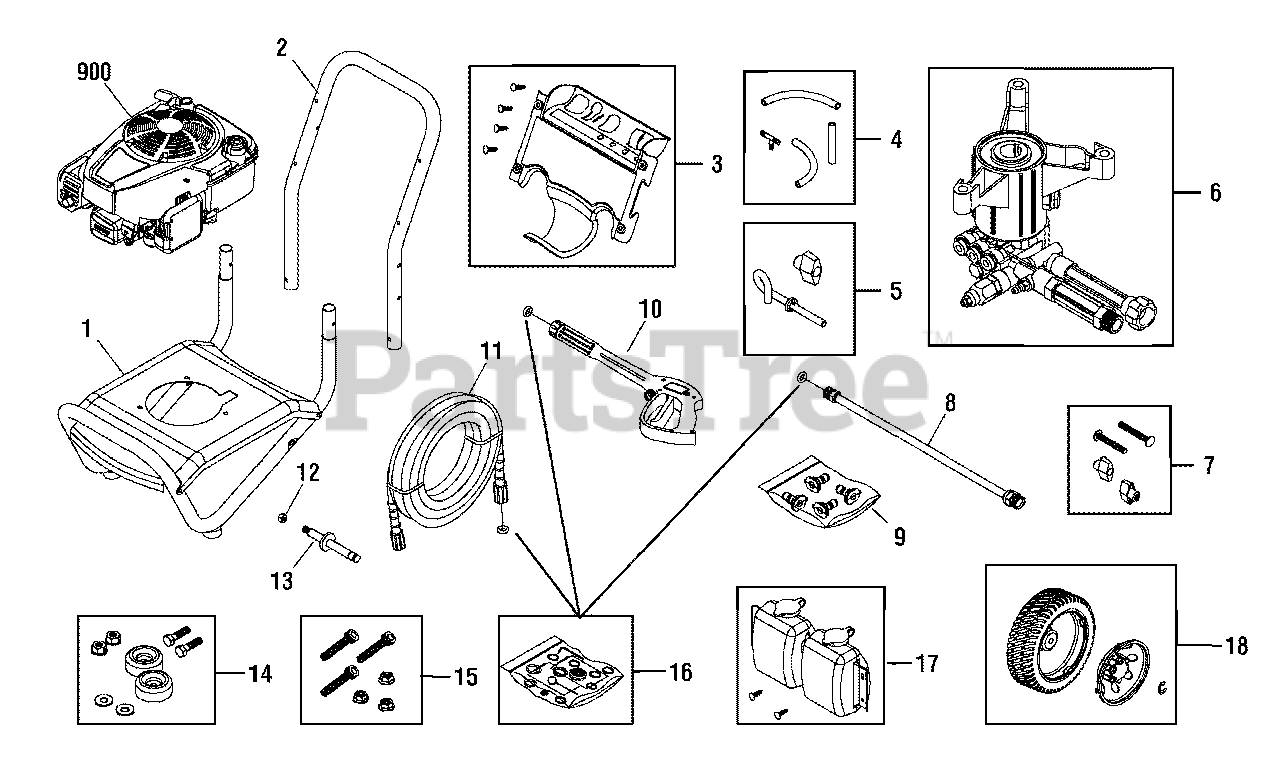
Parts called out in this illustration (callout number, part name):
4	KIT, Chemical Hose
6	PUMP
7	KIT, Hardware, Handle
8	EXTENSION, QC
9	KIT, QC Nozzles
10	GUN
11	HOSE
12	NUT
13	AXLE
14	MOUNT, Vibration
15	KIT, Hardware, Pump Mounting
16	KIT, O-Rings
900	* ENGINE
